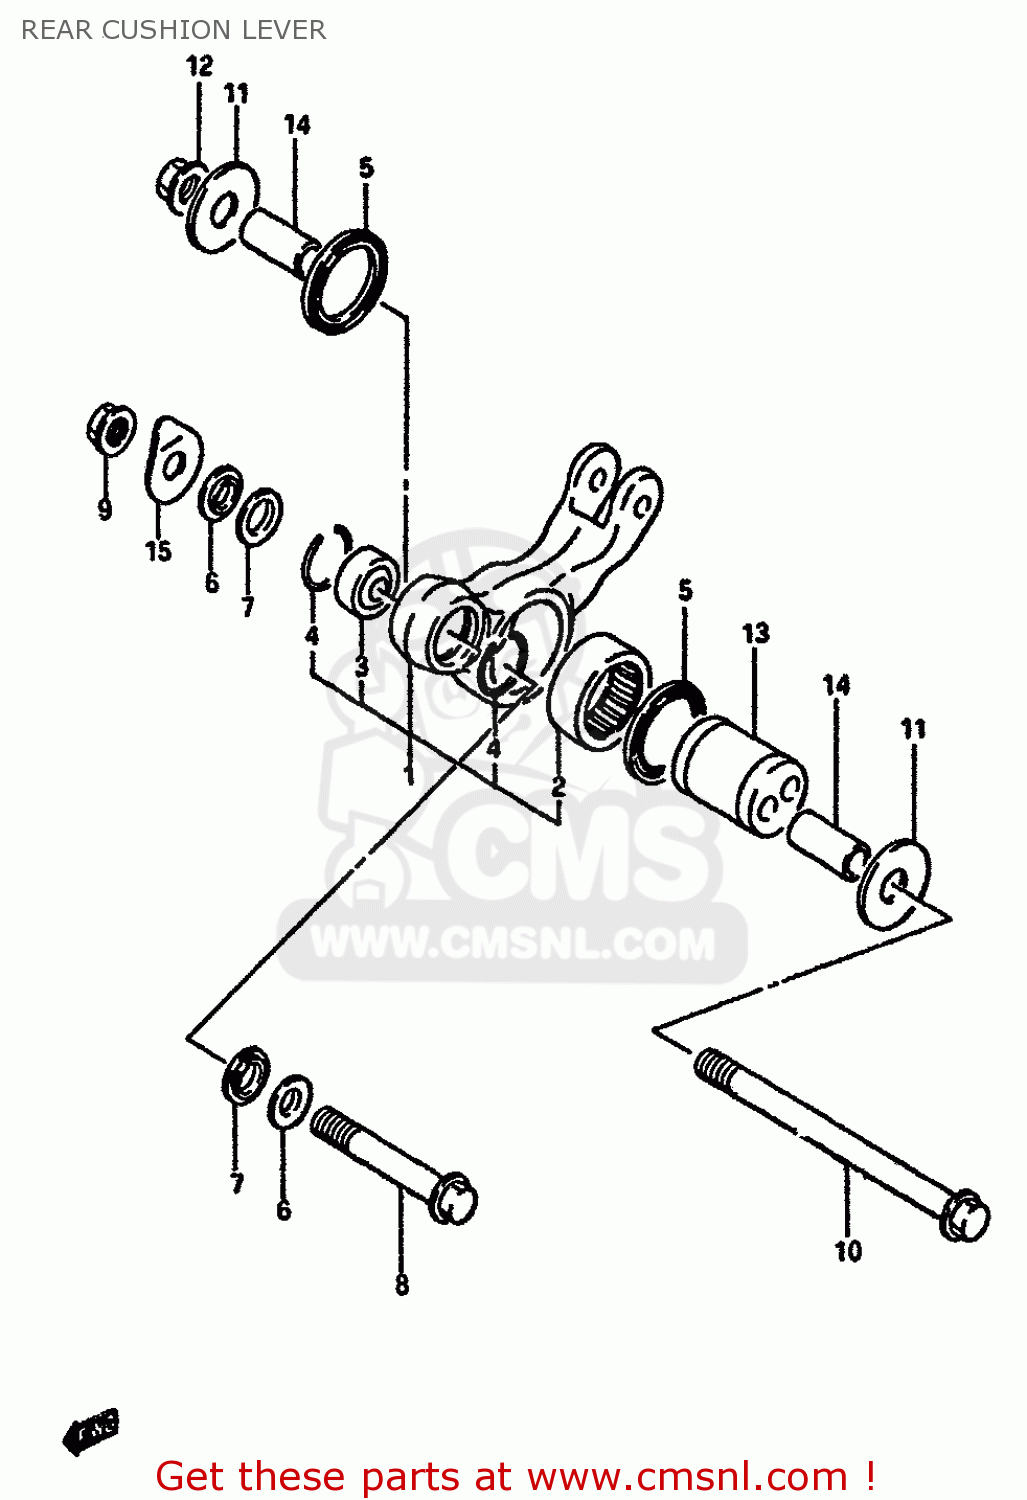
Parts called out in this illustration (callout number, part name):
1	LEVER SET,REAR CUSHION
2	BEARING(35X45X20)
3	BEARING(12X26X16)
4	RING,STOPPER
5	SEAL,INNER DUST
6	SPACER,RR CUSHION ROD
7	SEAL,RR CUSHION ROD DUST
8	BOLT,RR CUSHION LEVER FR
9	NUT 12MM
10	SHAFT
11	WASHER(12X40X2.5)
12	NUT 12MM
13	SPACER,REAR CUSHION ECCENTRIC
14	SPACER
15	SHIM,REAR CUSHION LEVER
